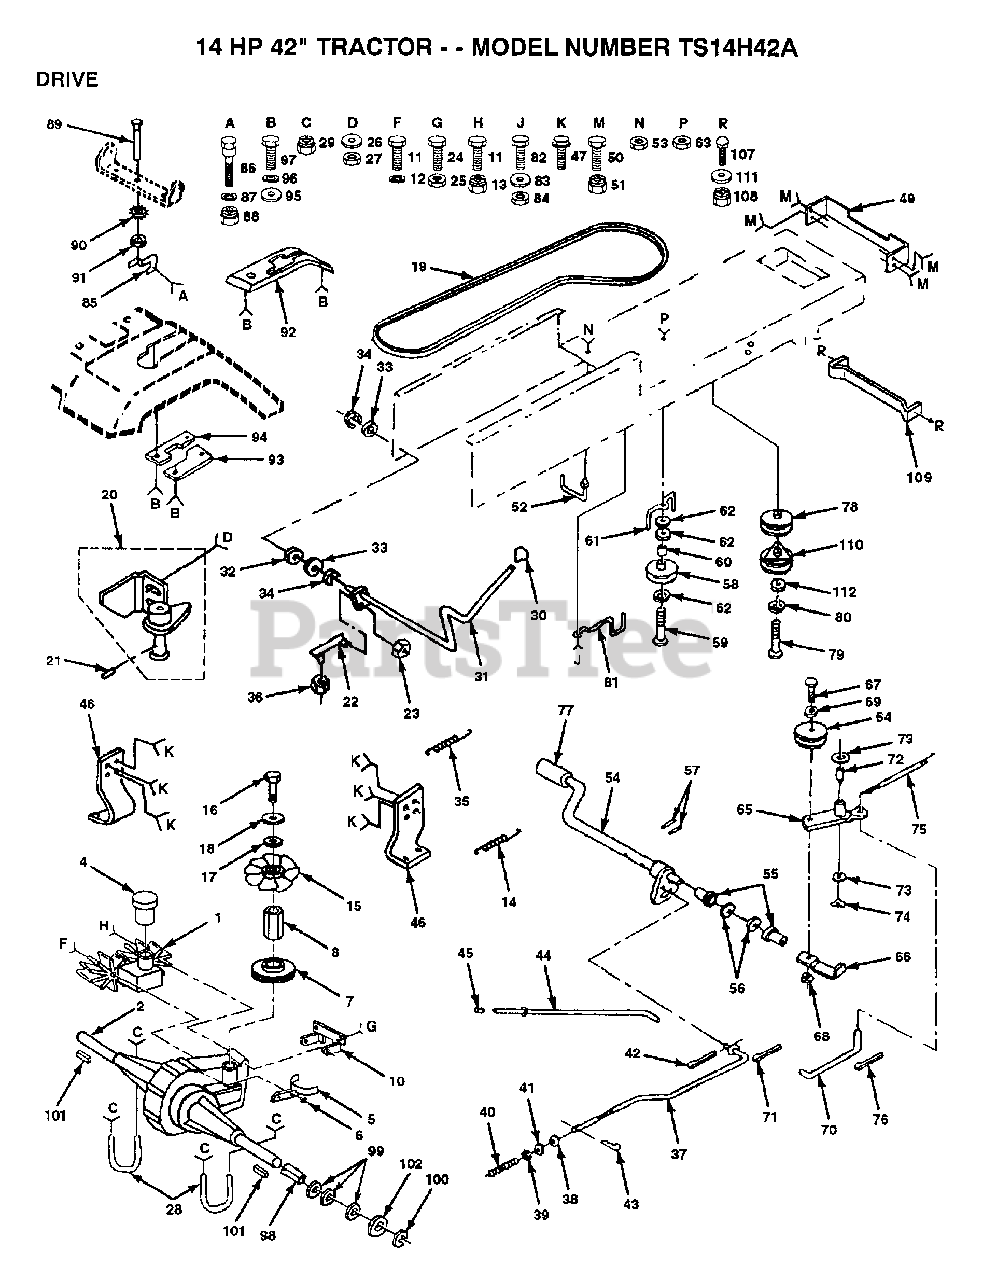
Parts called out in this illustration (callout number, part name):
1	PUMP.BDU-10S-114
2	TRANSAXLE.AGRIFAB
4	PUMP.2003081.
5	"GRD ASS'Y,BELT"
7	"PULLEY,TRANSAXLE"
8	STANDOFF
10	BRACKET
11	BOLT YT
12	LOCKWASHER
17	WASHER
18	LOCKWASHER
20	"FRICTION,PACK ASS"
21	"PIN,ROLL METRIC"
23	NUT WIZLOC T
26	WASHER
28	U BOLT
30	KNOB
31	"LEVER,CONTROL"
32	"BUSHING,PIVOT"
33	"WSHER,SHIM"
34	RING T
35	"SPRING,EXTENTION"
36	NUT WIZLOC T
37	"ROD, BRAKE"
38	NUT
39	NUT
40	SPRING ROD LT
41	WASHER
42	SPRING.RETAINER
43	RETAINER M
44	BRAKE PARK ROD
45	CAP PARKING BRAKE
46	"BRKT, MTG."
47	SCREW GTV
49	BRKT.MOUNTING
50	BOLT
52	"KEEPER,CENTERSPAN"
55	NYLON BEARING
56	WASHER LT
58	PULLEY.IDLER.FLAT
59	BOLT
60	SPACER T
61	BELT KEEPER LT
62	WASHER
65	ARM IDLER
66	RETAIN BELT
69	WASHER
70	"LINK, CLUTCH T"
71	COTTER PIN
72	"LY, BEARING"
73	WASHER LT
74	KLIP RING
75	"SPRING, RETURN LT"
76	COTTER PIN
77	PEDAL COVER T
78	PULLEY ENGINE
80	LOCKWASHER
81	KEEPER.BELT.ENG.L
82	BOLT
83	WASHER
85	"ARM,BYPASS CONTRO"
86	BOLT T
87	WASHER T
89	"CONSOLE,BYPASS"
90	LOCKWASHER
92	"CONSOLE,SHIFT FEN"
93	"PLATE,NEUTRAL RH"
94	"PLATE,NEUTRAL LH"
95	WASHER PM
96	LOCKWASHER
98	SPACER SPLIT
99	WASHER
100	E-RING LT
101	SQUARE KEY
102	WASHER
107	BOLT
109	BRACKET.ASM.MTG
111	WASHER T
112	WASHER
